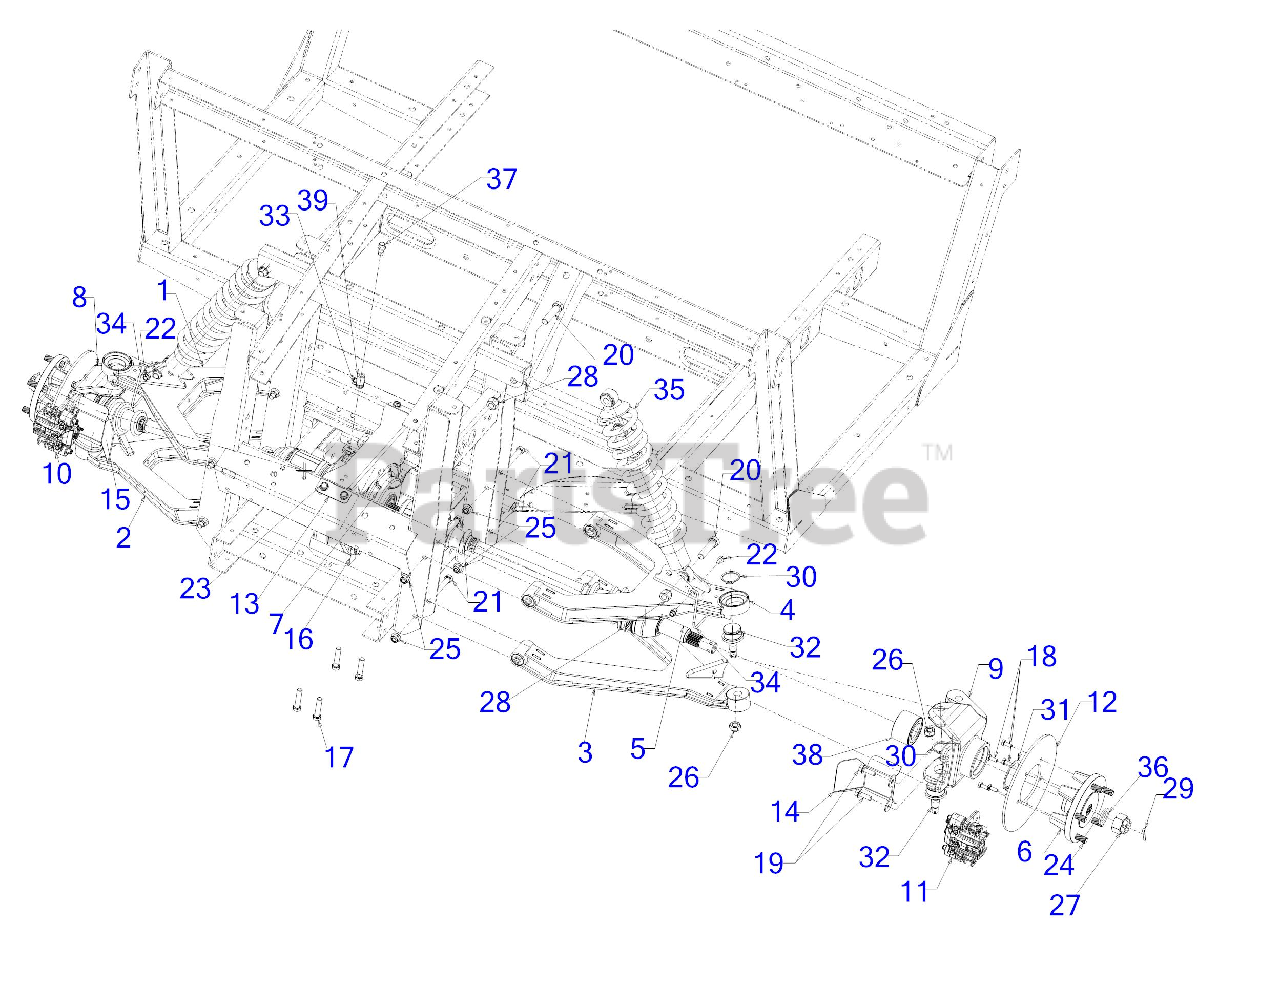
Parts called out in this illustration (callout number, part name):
1	UPPER CONTROL ASSEMBLY
2	LOWER CONTROL ASSEMBLY
3	LOWER CONTROL ASSEMBLY
4	UPPER CONTROL ASSEMBLY
5	CV JOINT AXLE ASSEMBLY
6	WHEEL HUB ASSEMBLY
7	DIFFERENTIAL ASSEMBLY
8	KNUCKLE HOUSING (FRONT/RH)
9	KNUCKLE HOUSING (FRONT/LH)
10	FRONT BRAKE CALIPER ASSEMBLY (RH)
11	FRONT BRAKE CALIPER ASSEMBLY (LH)
12	BRAKE DISC 8.00 x .188
13	FRONT DIFFERENTIAL MOUNT
14	STEERING SHIELD BRACKET (LH)
15	STEERING SHIELD BRACKET (RH)
17	HEX SCREW 3/8-16 x 1.75 GR5
18	SCREW 1/4-20 x .62 SPEC GR5
19	SCREW M8 x 1.25 x 25MM GR8.8
20	SCREW 1/2-13 x 2 GR5
21	SCREW 3/8-16 x 3 GR8
22	SCREW 1/4-20 X.500
23	SCREW 5/16-18 x .500
24	STUD 7/16-14 x 1.6
27	SLOTTED NUT22X1.5
28	HEX LOCK NUT NYLON
29	COTTER PIN-5/32 DIA
30	RETAINING RING
31	RETAINING RING
32	BALL JOINT
33	HOSE CLAMP
34	BRAKE LINE WIRE
35	FRONT SHOCK ABSORBER
36	THRUST WASHER
38	DOUBLE ROW BEARING
39	FUEL HOSE LOW PERMEATION
